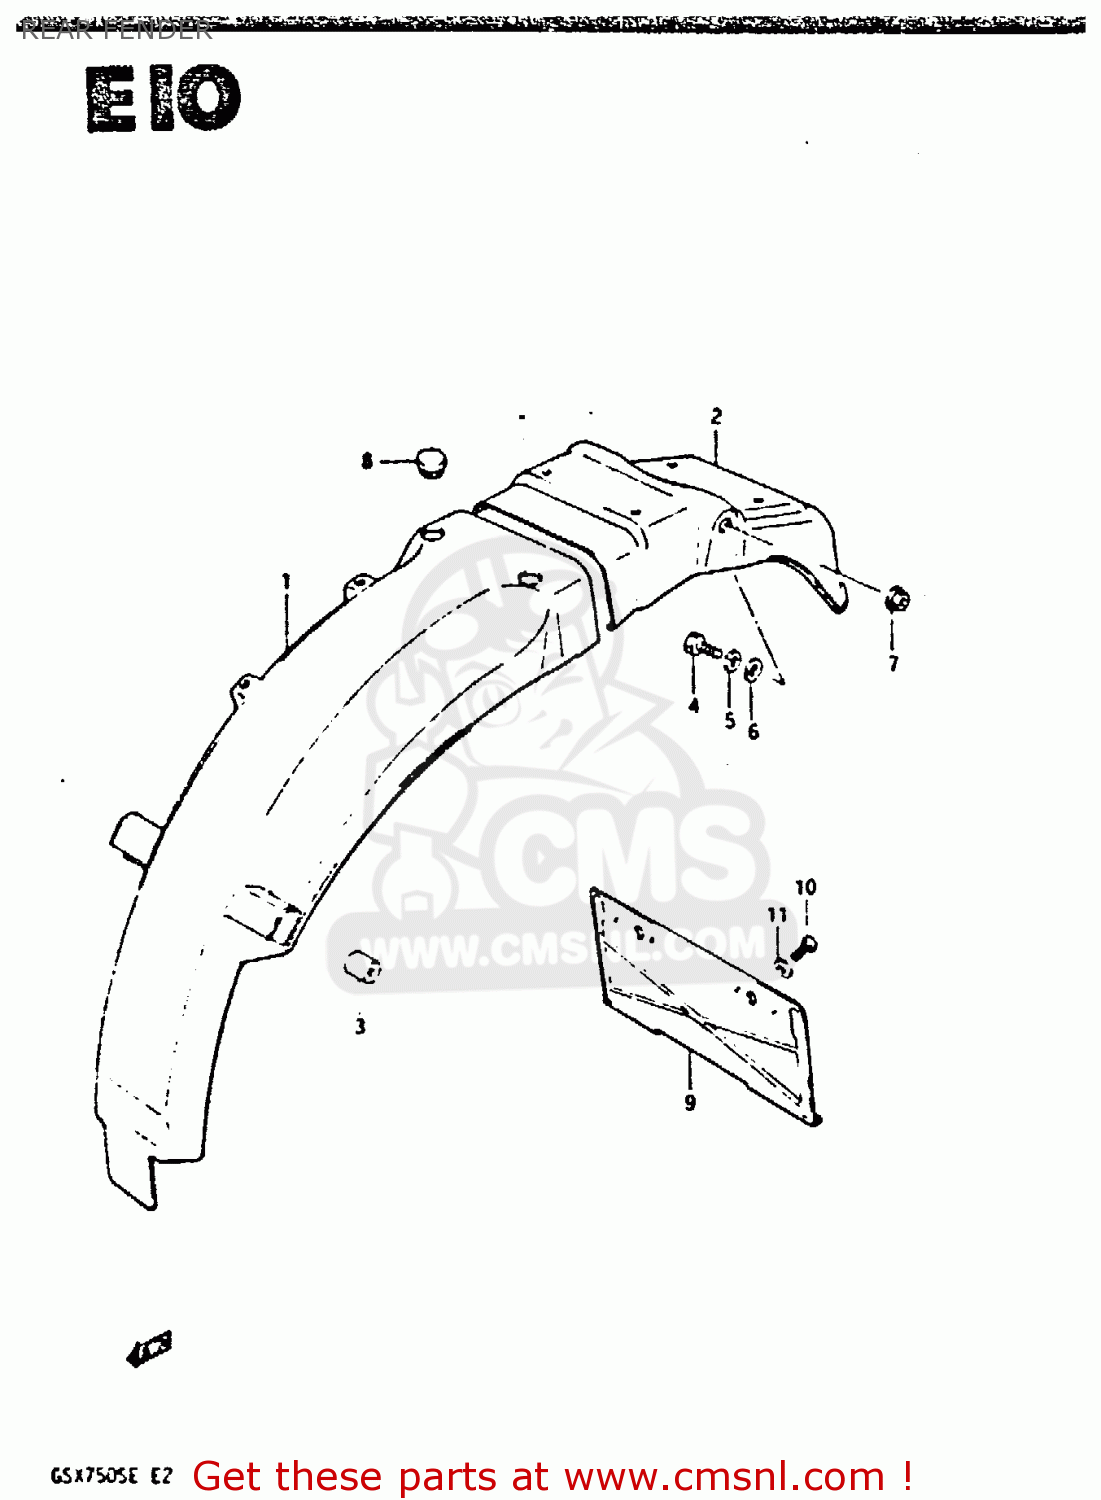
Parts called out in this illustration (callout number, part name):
1	BODY,REAR FENDER,FRONT
2	REINFORCEMENT
3	CUSHION
4	BOLT
5	WASHER,LOCK,8.
6	WASHER 8MM
7	NUT, WHEEL SET
8	PLUG(OD:22)
9	HOLDER,RR LICENSE PLATE
10	BOLT
11	WASHER
